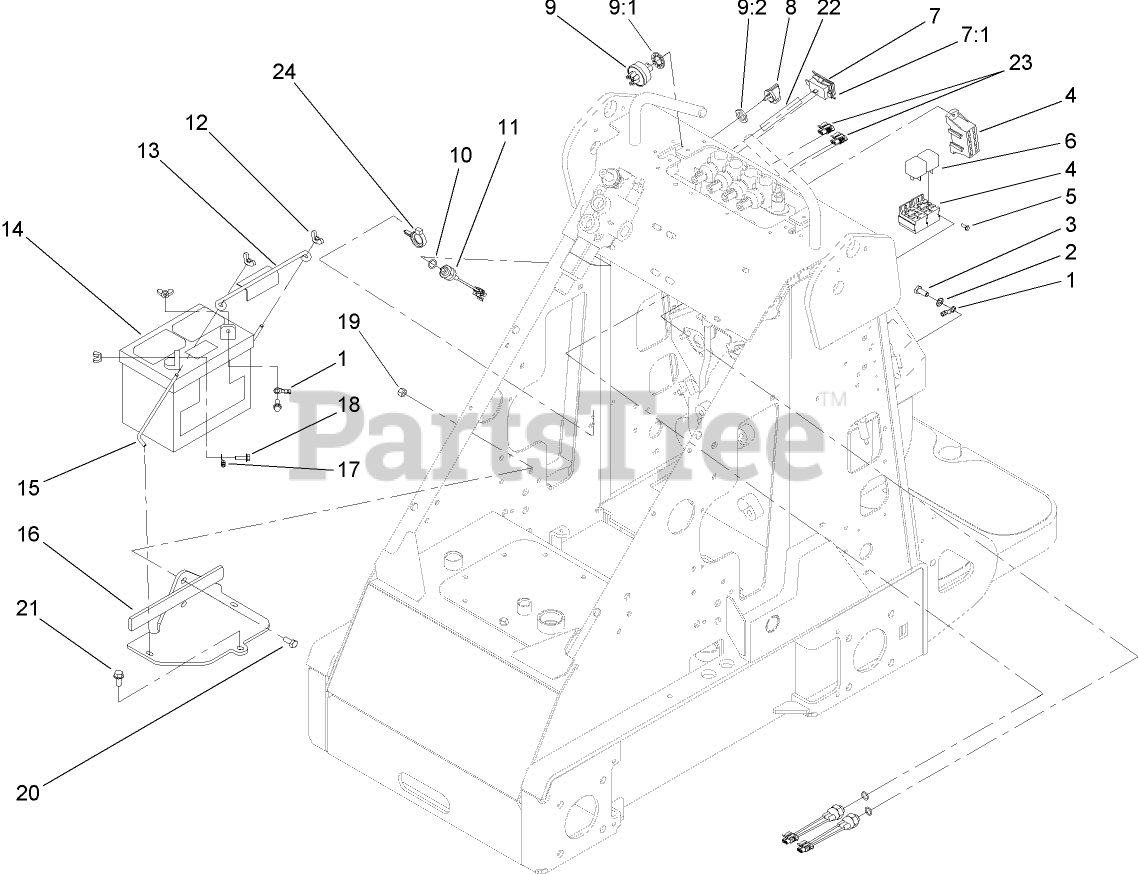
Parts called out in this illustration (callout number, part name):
1	WIRE ASM
2	WASHER-LOCK
3	SCREW-HH
4	HARNESS-WIRE
5	SCREW-HWHTF
6	RELAY
7	HOURMETER-INDUCTIVE
7:1	CLIP-MOUNTING
8	KEY-IGNITION
9	IGNITION SWITCH ASM
9:1	WASHER-LOCK
10	O-RING
11	SWITCH-BALL
12	NUT-WING
13	HOLDDOWN-BATTERY
14	BATTERY-DRY
15	RETAINER-BATTERY
16	BATTERY MOUNT ASM
17	CABLE-POSITIVE
18	SCREW-HHF
19	NUT-LOCK, NI
20	SCREW-HH
21	SCREW-HWHTF
22	WIRE-HOURMETER
23	Connector-Female
24	CLAMP-HOSE
